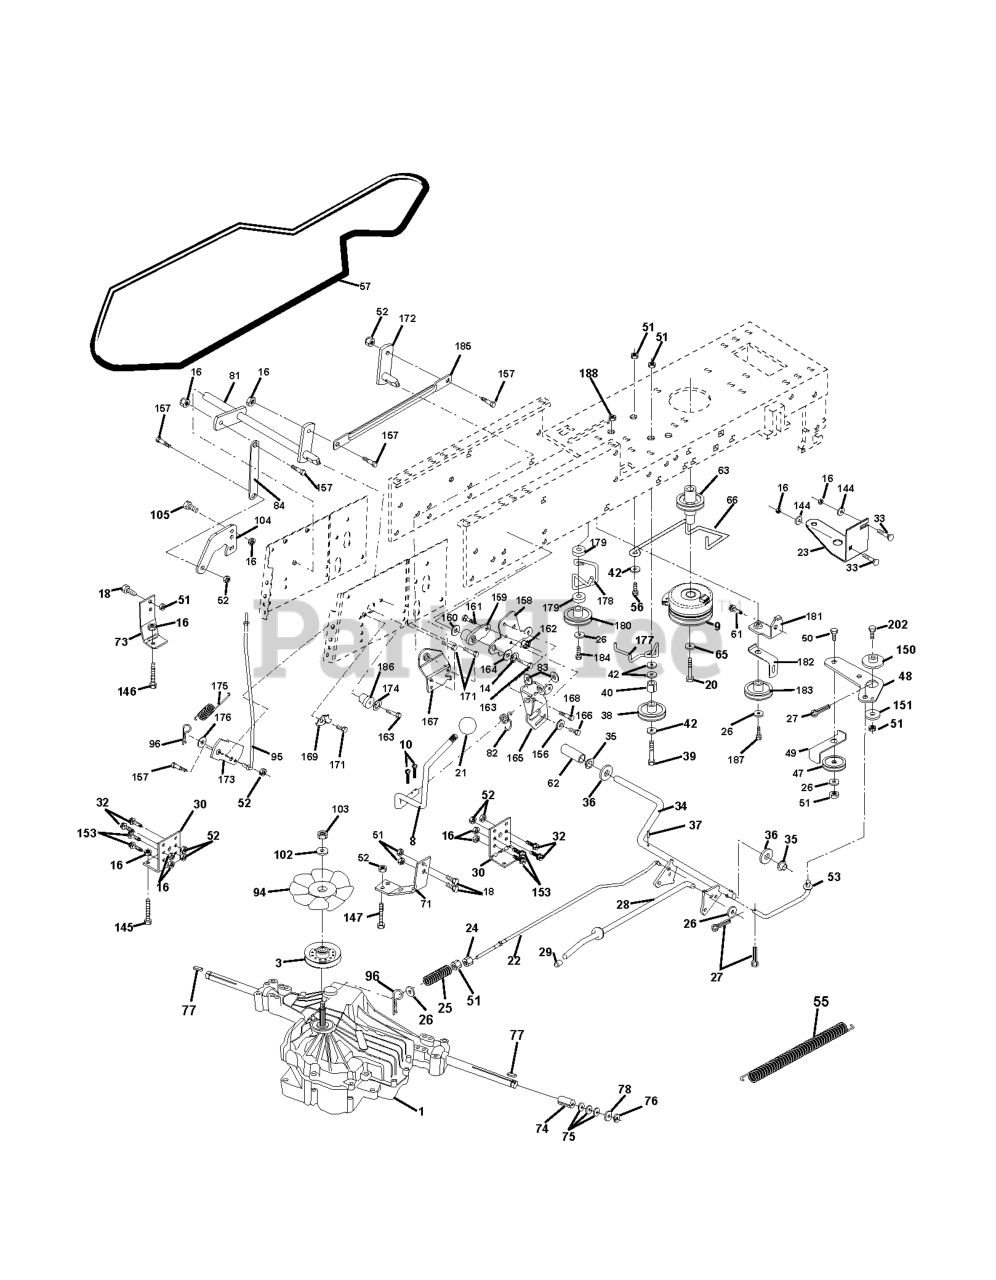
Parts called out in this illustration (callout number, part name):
3	PULLEY, TRANSAXLE
8	ROD.SHIFT.FENDER.ADJ.LT.CRD
10	PIN COTTER
14	LOCKWASHER
16	NUT.71038.31-18.HEX.NYLOCK
19	NUT
20	BOLT HEX
21	KNOB.DUCKHEAD.1/2
23	BRACKET.ASM.CLUTCH
24	NUT
25	SPRING ROD LT
26	WASHER
27	COTTER PIN
28	ROD BRAKE PARK LT
29	PLUNGER CAP
30	BRACKET TRANSAXLE
32	BOLT
33	RP BOLT 5/16-18 X3/4 ZN/YEL GR
35	BEARING.NYLON
37	DRIVE PIN
38	PULLEY.FLAT
42	WASHER
47	IDLER PULLEY
48	BELLCRANK, CLUTCH
49	RETAIN BELT
50	BOLT
52	LOCKNUT
53	LINK, CLUTCH LT
55	SPRING, RETURN LT
57	V-BELT.0650.CRD.TRACTOR
61	SCREW
62	COVER, PEDAL (1 2)
63	PULLEY, CLUTCH ELECT EVX
65	LOCKWASHER
66	KEEPER BELT ENGINE
71	STRAP LH TORQUE
73	STRAP TORQUE RH HYDRO
74	SPACER SPLIT
77	SQUARE KEY
82	SPRING,TORSION
83	WASHER
84	LINK TRANSAXLE
94	FAN 7" HYDRO
95	BYPASS CONTROL ASM
96	RETAINER M
103	NUT.HEX.1/2-20
104	CONTROL ARM
144	Washer 11/32 x 5/8 x 16 Ga SD
147	Bolt Hex Flanged 5/16-18 Unc x 2
150	BUSHING.BELLCRANK.GRD.DR
151	WASHER 12/32X2X10GA
153	BOLT RB
156	WASHER.SRRTD.5/16
157	BOLT SHOULDER 5/16-18
158	BRACKET
159	HUB
160	Washer 29/32 x 1 - 1/4 x 16 Ga.
161	BOLT
162	NUT.CROWNLOCK.1/4
164	Washer 5/8 x .281 x 10 Ga.
165	RP BRACKET
167	BRACKET.SUPT.SHIFT.CRD
168	BOLT.SHOULDER.5/16-18X
169	PLATE.FASTENING.CROSS.SHAFT
174	LOCKWASHER
175	SPRING.BYPASS.CRD
176	Washer 7/32 x 1/2 x 16 Gauge
180	PULLEY.FLAT.IDLER
181	BRKT.IDLER.GRD.DR.CRD
182	KEEPER BELT
183	PULLEY.V-IDLER
184	SCREW.HXWSH.3/8
186	HUB.TAPERED.ROUND.CRD
187	SCREW
188	SNAP BUSHING T
202	BOLT.3/8-16X1.50
